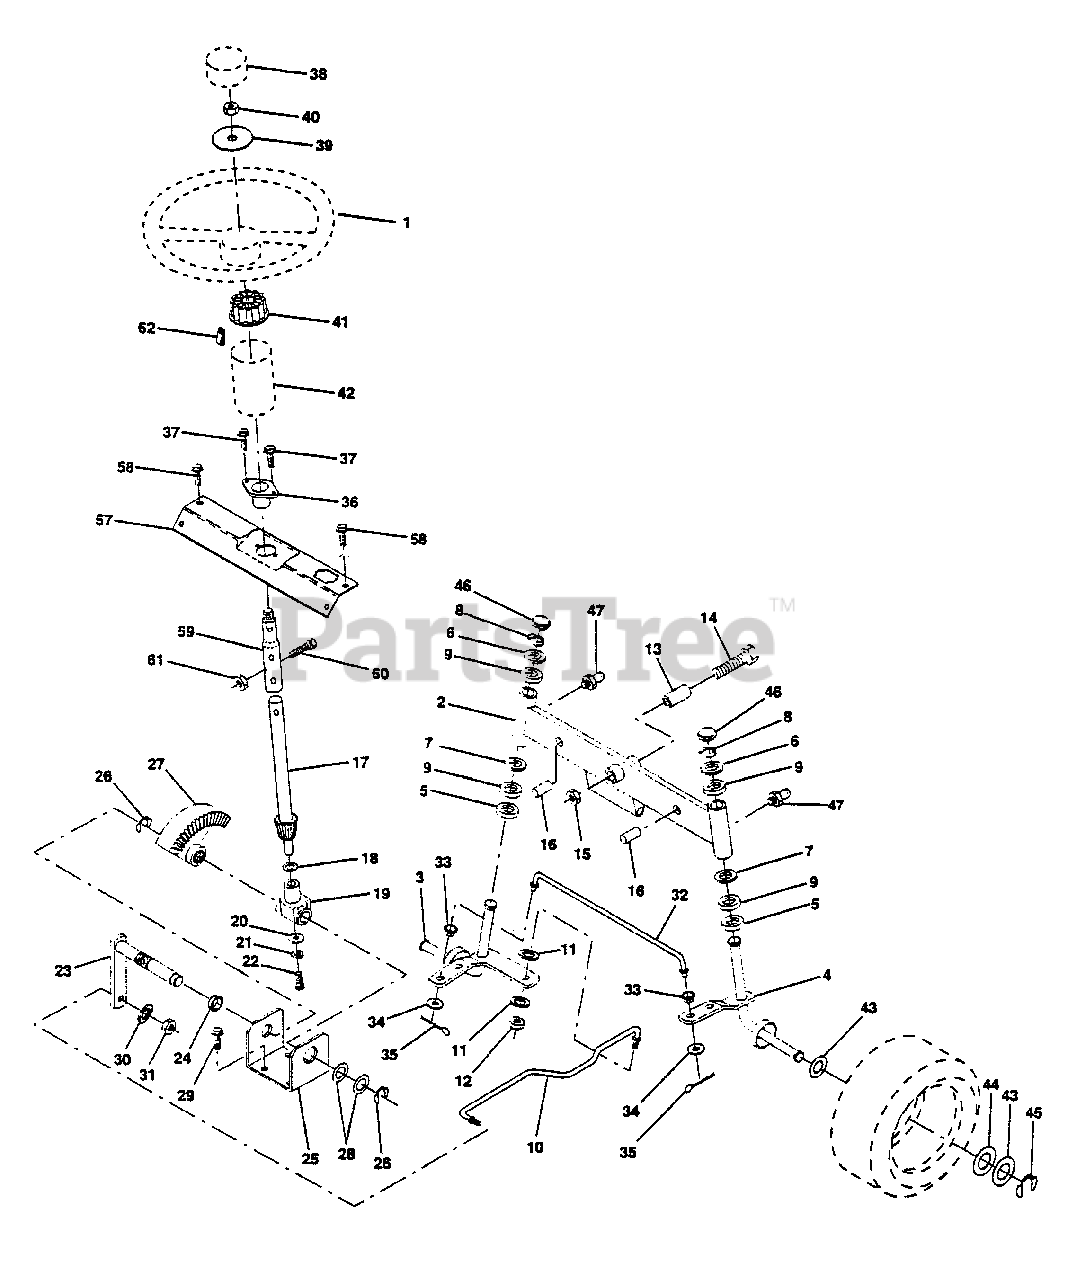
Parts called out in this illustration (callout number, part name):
1	Wheel Steering Auto Blk
2	Axle Asm Fr LT W/gzks 38/42
3	Spindle Asm LH
4	Spindle Asm RH
5	Bearing Race Thrust Harden
6	Washer 25/32 X 1-5/8 X 16 Ga
7	Washer 27/32 X 1-1/4 X 16 Ga
8	Ring Klip #t5304-75
9	Bearing Col Strg Blk
10	Link Drag Sol Ball Jt 20 064
11	Washer Lock Hvy Hlcl Spr 3/8
12	Nut Fin Hex 3/8-24 Unf
13	Spacer Bearing Axle Front
14	Bolt Hex 5/8-11 Unc X 3-1/2
15	Nut Lock Flange 5/8-11 Unc
16	Pin Axle 5/8 X 1 55/1 54 Lg
17	Shaft Asm Strg Private Label
18	Washer Thrust 515x 750x 033
19	Support Shaft
20	Washer Shim 1/4 X 5/8 X 062
21	Washer Lock Hvy Helical 1/4
22	Screw Hex Socket 1/4-20 X 5/8
23	Shaft Asm Pittman
24	Nyliner Snap In
25	Bracket Steering
26	Ring Klip M5304-75
27	Gear Sector
28	Bearing Race Thrust Harden
29	Screw Thdrol 3/8-16x3/4 Ty-tt
30	Washer Lock Hvy Hlcl Spr 3/8
31	Nut Fin Hex 3/8-24 Unf
32	Rod Tie Wire Form 19 75 Mech
33	Bushing Link Drag Blk LR
34	Washer 13/32 X 7/8 X 16 Ga
35	Pin Cotter 1/8 X 3/4 Cad
36	Bushing Strg
37	Screw Slftp #10-16 X 1/2 Ty-b
38	Insert Cap Strg Wh Au
39	Washer 13/32 X 2-3/8 X 8 Ga
40	Nut Lock Center 3/8-24unf
41	Adaptor Wheel Strg 640/ 635id
42	Boot Steering Shaft
43	Washer 25/32 X 1 1/4 X 16 Ga
44	Washer 25/32 X 1-5/8 X 16 Ga
45	Ring Klip #t5304-75
46	Cap Spindle Fr Top Blk
47	Fitting Grease
57	Support Shaft Steering
58	Screw Hex Wsh Thdrol 1/4-20 x 3/4
59	Shaft Extention Steering
60	Bolt Fin Hex 5/16-18 Unc x 1-1/4
61	Nut Lock Hex w/Ins 5/16-18
62	Clip Tinnerman
